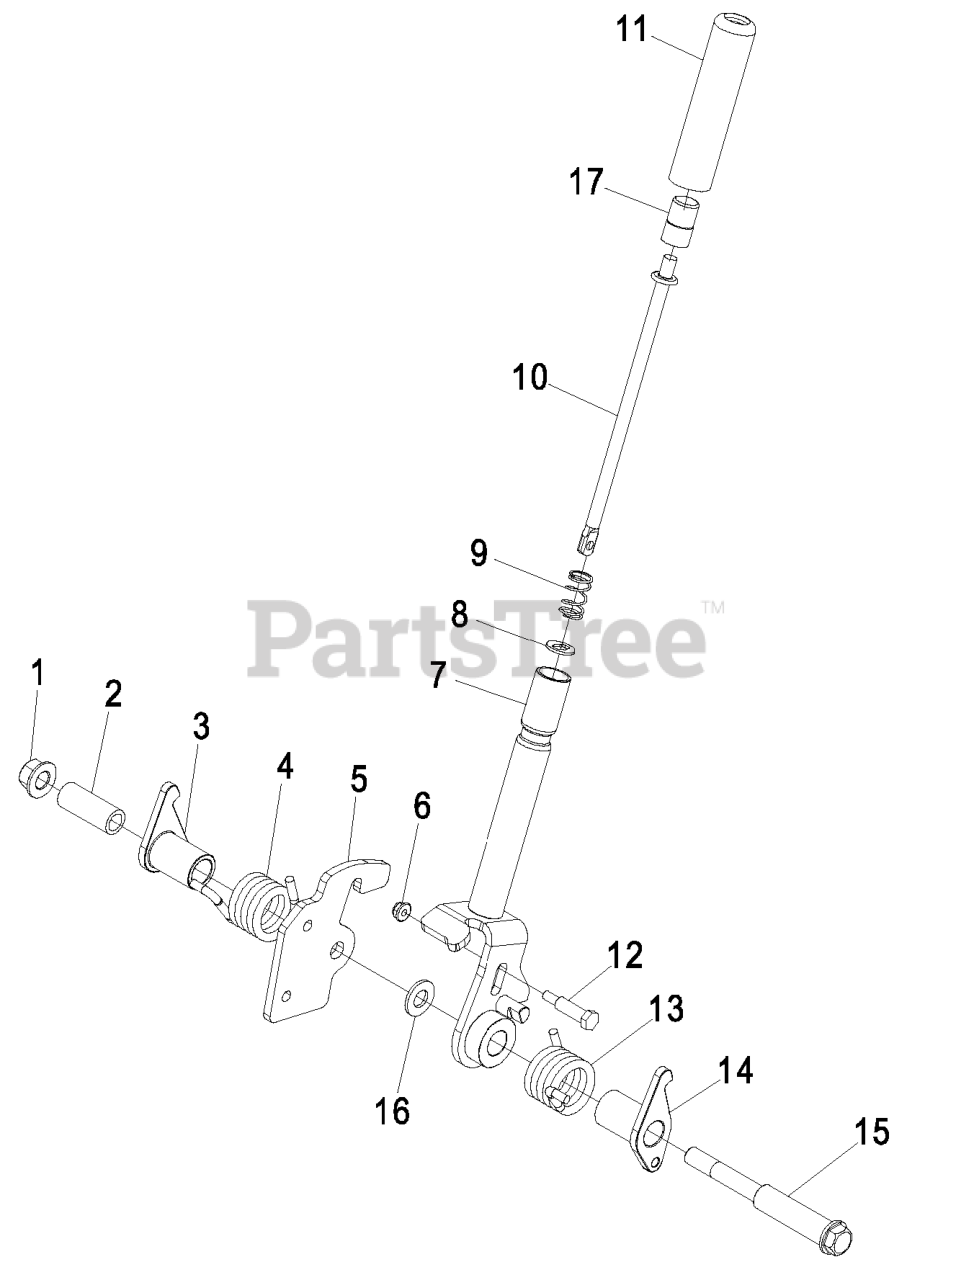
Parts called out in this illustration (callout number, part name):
1	Nut-Lock 1/2-13
3	ARM-BRAKE, LH
4	SPRING-TORSION, RH
5	PLATE-LATCH
7	BRAKE HANDLE ASM
8	WASHER-SPECIAL
9	SPRING-COMPRESSION
10	ROD-RELEASE, BRAKE
12	BOLT-SHOULDER
13	SPRING-TORSION, LH
14	ARM-BRAKE, RH
15	BOLT-SHOULDER
16	WASHER-FLAT
